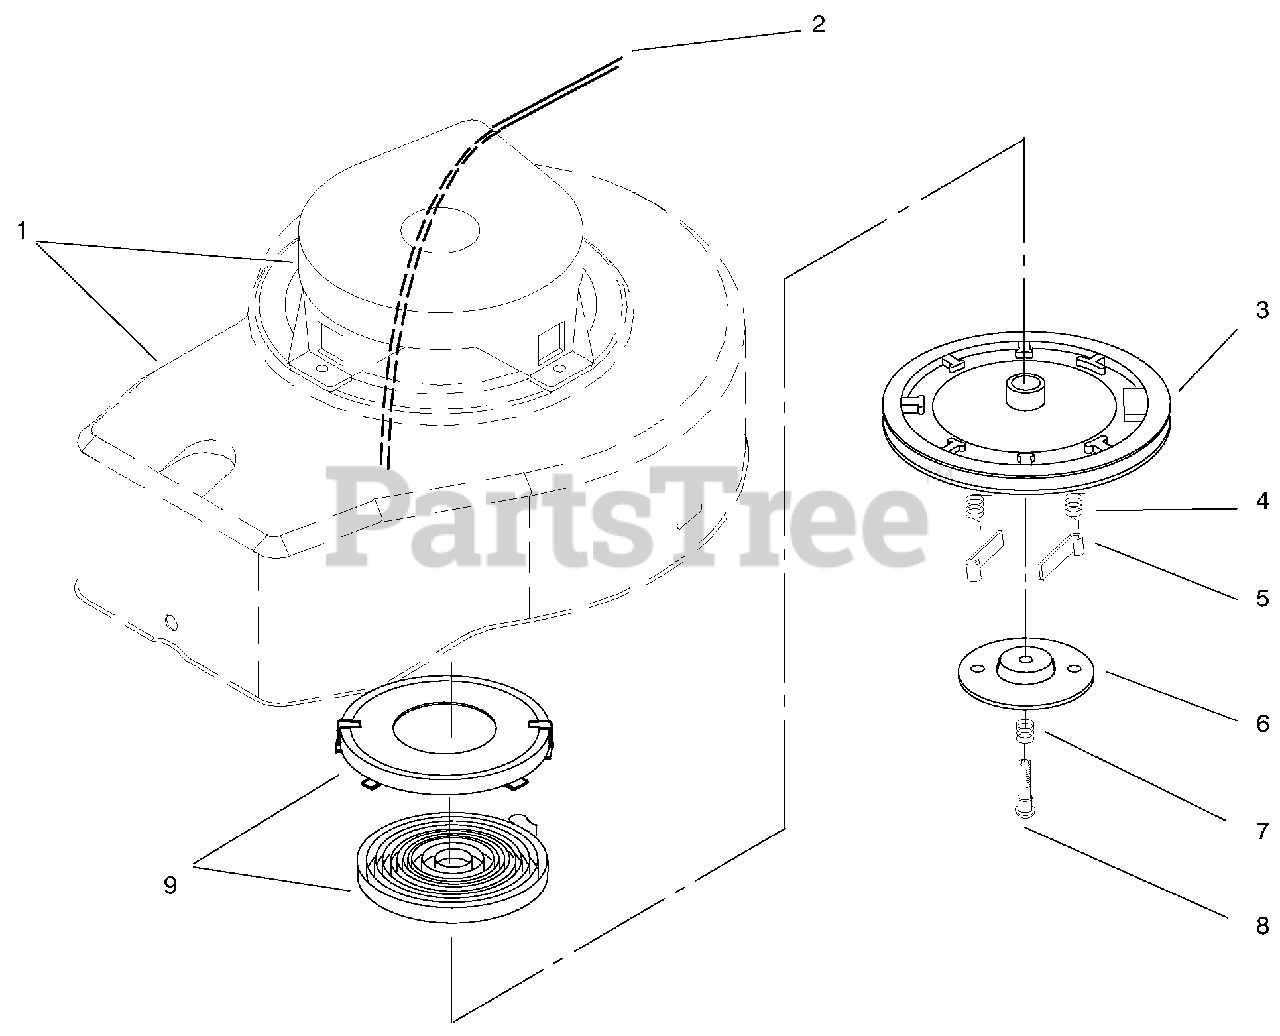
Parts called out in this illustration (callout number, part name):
1	Housing Assembly
2	Rope-Starter
3	Pulley Assembly
4	Spring-Dog
6	Retainer
9	Spring Keeper Assembly
